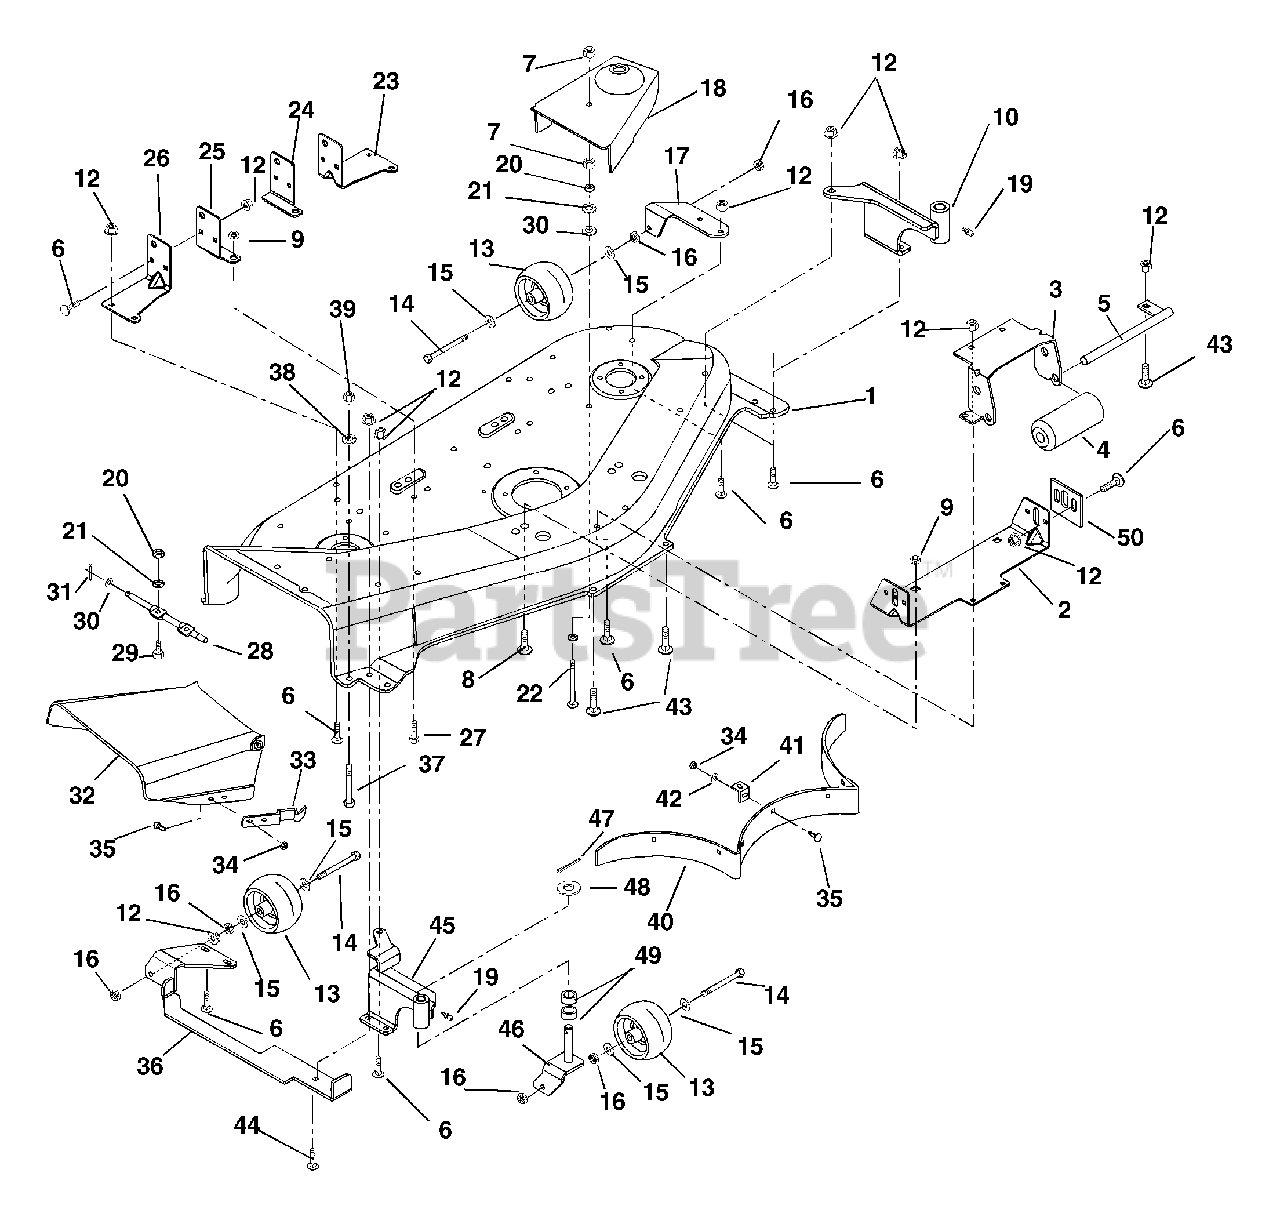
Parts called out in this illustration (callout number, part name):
1	Mower Pan Head w/Decals 48"
2	Front Hanger
3	Bracket, Roller
4	Roller
5	Roller Shaft
6	Bolt-Round Head Square Neck .31-18 x .75 Grade 5
7	Nut-Locking-Center .312-18
8	Bolt-Round Head Square Neck .50-13 x .75 - Short Neck
9	Nut-Locking-Center .50-13 Grade 5
10	Weldment-Left Front
11	Bolt-Round Head Square Neck .31-18 x .75
12	Nut-Locking-Top-Flange .31-18
13	Roller
14	Bolt-Hex .38-16 x 3.50 Grade 5
15	Washer-Flat-Steel .38 x .875 x .083
16	Nut-Locking-Center .375-16
17	Bracket-Left Rear
18	Belt Cover Right Hand 48"
18	Belt Cover Left Hand 48"
19	Fitting-Lube .25-20 x .256
20	Nut-Locking .312-18
21	Washer-Locking .31 x .078
22	Bolt-Round Head Square Neck .31-18 x 3.25
23	Left Hand Rear Hanger
24	Left Hand Rear Hanger Support
25	Right Hand Rear Hanger Support
26	Right Hand Rear Hanger
27	Bolt-Hex .50-13 x 1.00 Grade 5
28	Hinge Pin
29	Bolt-Hex .31-18 x .75 Grade 5
30	Washer-Flat-Steel .406 x .812 x .065
31	Pin-Cotter .09 x .75
32	Chute Extension
33	Flat Spring
34	Nut-Locking-Center .25-20
35	Bolt-Round Head Square Neck .25-20 x .50 Grade 5
36	Weldment-Right Rear
37	Bolt-Round Head Square Neck .38-16 x 2.50 Grade 5
38	Washer-Lock .375 x .155
39	Nut-Hex .375-16
40	Baffle
41	Baffle Tab
42	Washer-Flat-Steel .281 x .620 x .065
43	Bolt-Round Head Square Neck .31-18 x 1.50 Grade 5
44	Bolt-Round Head Square Neck .31-18 x 1.00 Grade 5
45	Weldment-Right Front
46	Caster Fork Weldment
47	Pin-Cotter .18 x 1.25
48	Washer-Flat-Steel .630 x 1.005 x .062
49	Bushing-Sleeve .625 x .750 x .500
50	Mower Adjustment Tab
